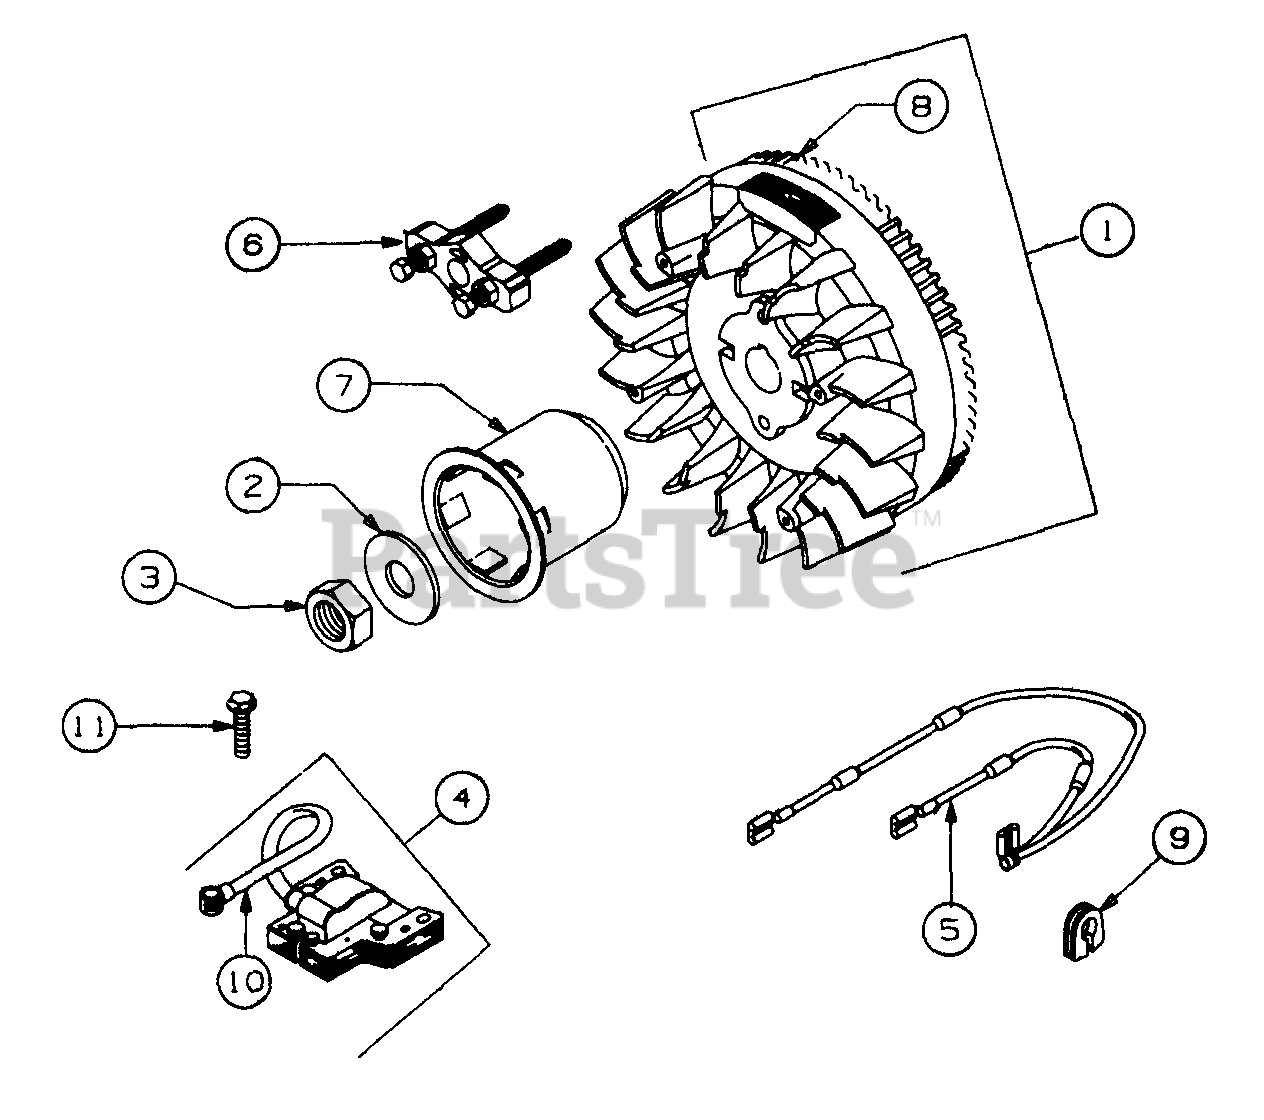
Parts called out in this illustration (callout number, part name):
1	Flywheel, Magneto
2	Washer, Spring
4	Armature, Magneto
5	Wire Assy
6	Puller, Flywheel
7	Hub, Starter
8	Gear, Ring
9	Grommet
10	Terminal, Ignition Cable
11	Screw, Mounting
